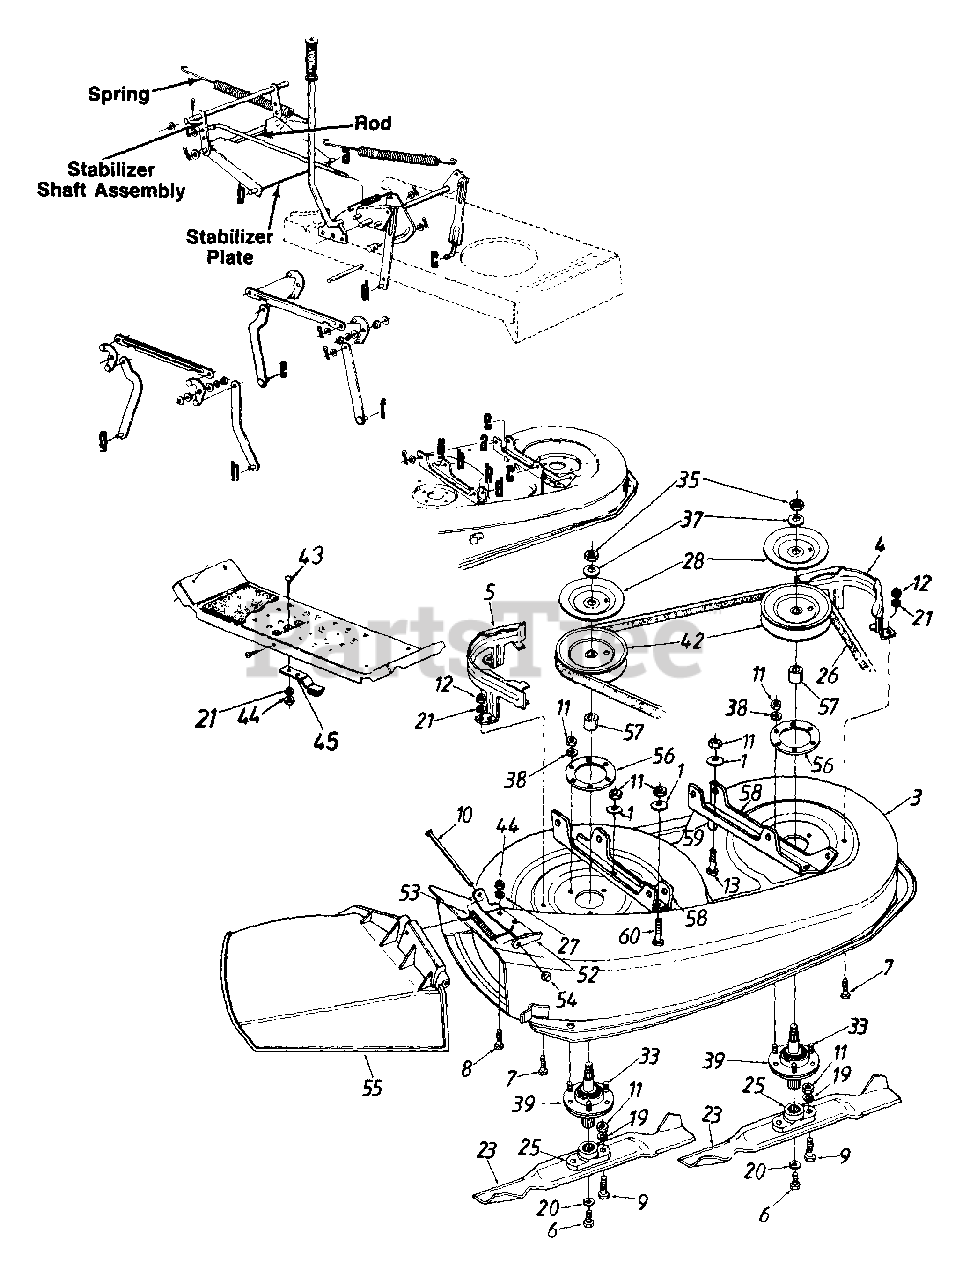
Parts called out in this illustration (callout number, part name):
1	Bell-Wash. .345" I.D.
3	36" Deep Deck Ass'y.
7	Hex Bolt 1/4-28 x .62"
8	Hex Bolt 1/4-20 x .62"
9	Hex Bolt Special 5/16-24 x 1.0"
10	Hinge Pin
11	Hex Nut 5/16-24 Thd.
12	Hex Nut 1/4-28 Thd.
13	Hex Bolt 5/16-24 x 1.25" Lg.
19	L-Wash. 5/16" I.D.
20	L-Wash. 3/8" I.D.- H.D.
21	L-Wash. 1/4" I.D.
23	High-Lift Blade
25	Blade Adapter
26	V-Belt
27	Bell-Wash. 1/4" I.D.
28	Brake Disc
33	Rib Neck Bolt 5/16-24 x .84" Lg.
35	Hex Jam Nut 5/8-18 Thd.
37	L-Wash. 5/8" I.D.
38	L-Wash. 5/16" I.D.
39	Blade Spindle Ass'y. Comp.
42	5" Dia. Pulley
43	Carr. Bolt 1/4-20 x .62"
44	Hex Nut 1/4-20 Thd.
45	Blade Brake Ass'y.
52	Hinge Mtg. Brkt.
53	Torsion Spring
54	Push Nut
55	Chute Ass'y. Comp.
56	Reinforcement Plate
57	Spacer
60	Hex Bolt 5/16-24 x .75" Lg.
